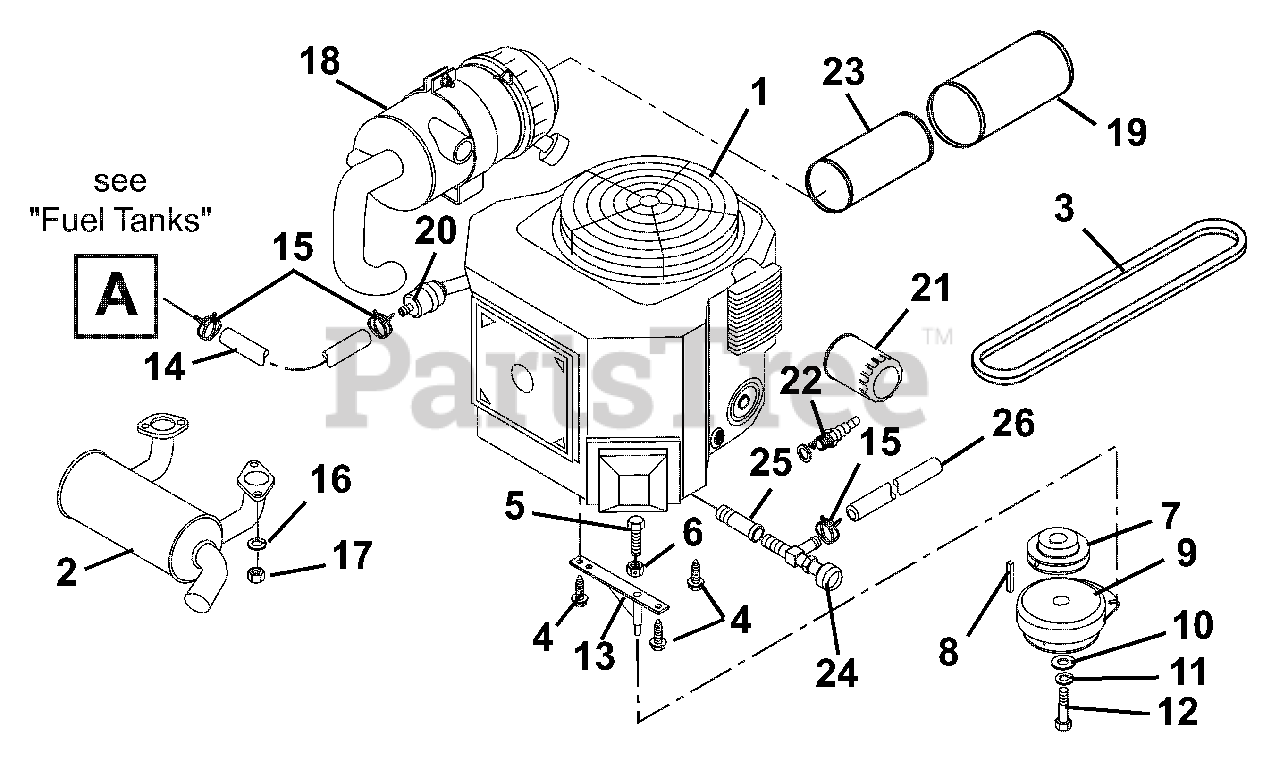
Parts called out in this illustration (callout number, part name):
1	ENGINE, 19HP KAWASAKI
2	MUFFLER, KAW (INTERMEDIATE-Z)
3	V-BELT, HA-RAW EDGE
4	@SCR-TAP .38-16X1.00 HWH TR YZ
5	@BLT-HEX .31-18X1.50 GR5 YWZC
6	@NUT-LK-TOP-FLG .31-18 YWZC
7	PLY-V 4.00 X 1.12 KEYWAY 1.54
8	KEY-SQ .25X.625X.25 SAE 8630
9	CLUTCH, ELECTRIC (WARNER)
10	WSHR-FL-STL .515X1.625X.250 YZ
11	@WSHR-LK .44X.109 REG YWZC
12	BLT-HEX .44-20X2.50 GR5 YWZC
13	WMT, CLUTCH ANCHOR
14	GAS LINE-BULK 1/4" I.D.
15	CLAMP-HOSE WIRE .490/.510X.116
16	@WSHR-LK .31X.078 REG YWZC
17	NUT-HEX M8-1.25 YWZC
18	AIR CLEANER ASSEMBLY
19	ELEMENT, OUTER PRIMARY
20	FILTER, FUEL - KOH CV20
21	FILTER,OIL - KAW
22	PLUG, SPARK
23	ELEMENT, INNER SAFETY
24	COCK, OIL DRAIN
25	ADAPTER, OIL DRAIN
26	GAS LINE-BULK 1/4" I.D.
NS	KIT,BRAKE POLE MODULE REPLACE
